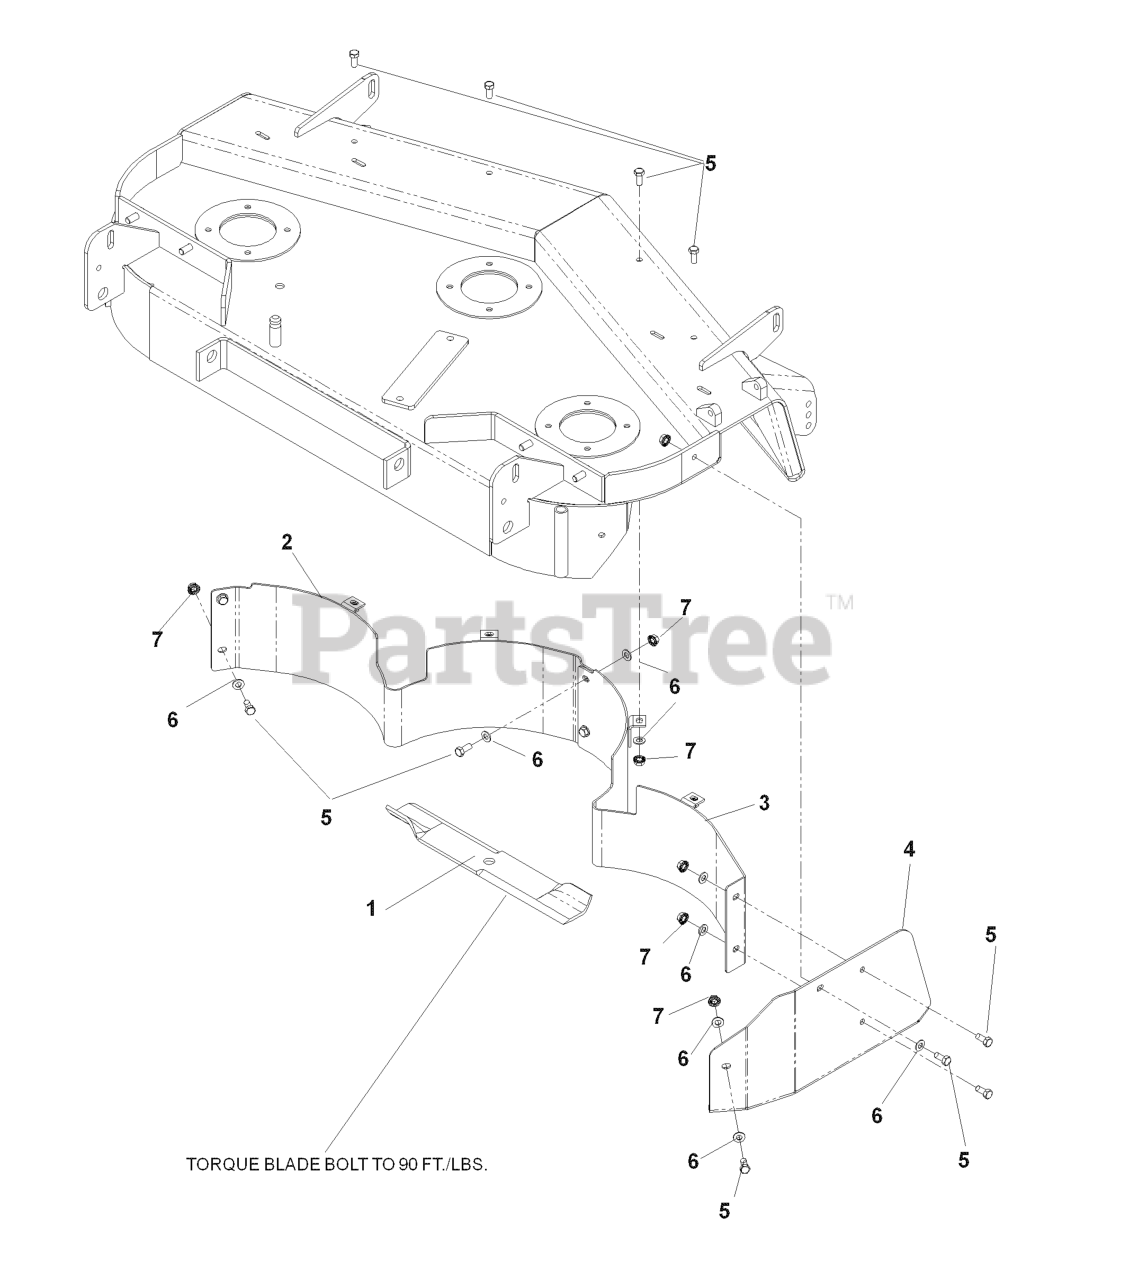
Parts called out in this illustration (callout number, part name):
1	BLADE MULCH 14-7/8"
2	MULCH BAFFLE, LEFT, 42
3	BAFFLE WLDMT, 42" R.H. MULCH
4	MULCH CAP 42"
5	HCS 5/16C X 3/4
6	FLAT WASHER 5/16 SAE
7	NUT 5/16C WHIZ
